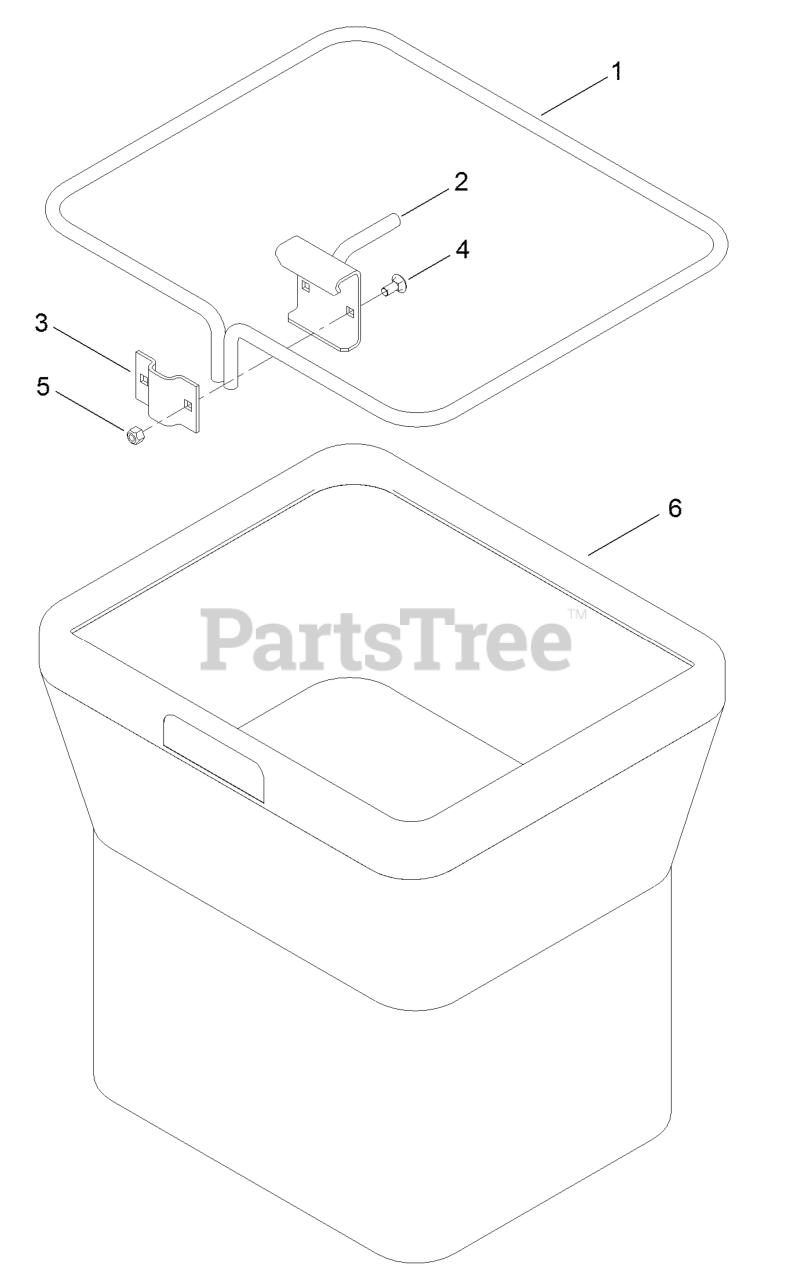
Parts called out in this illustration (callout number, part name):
1	FRAME-BAG
4	BOLT-CARR
5	NUT-LOCK, NI
